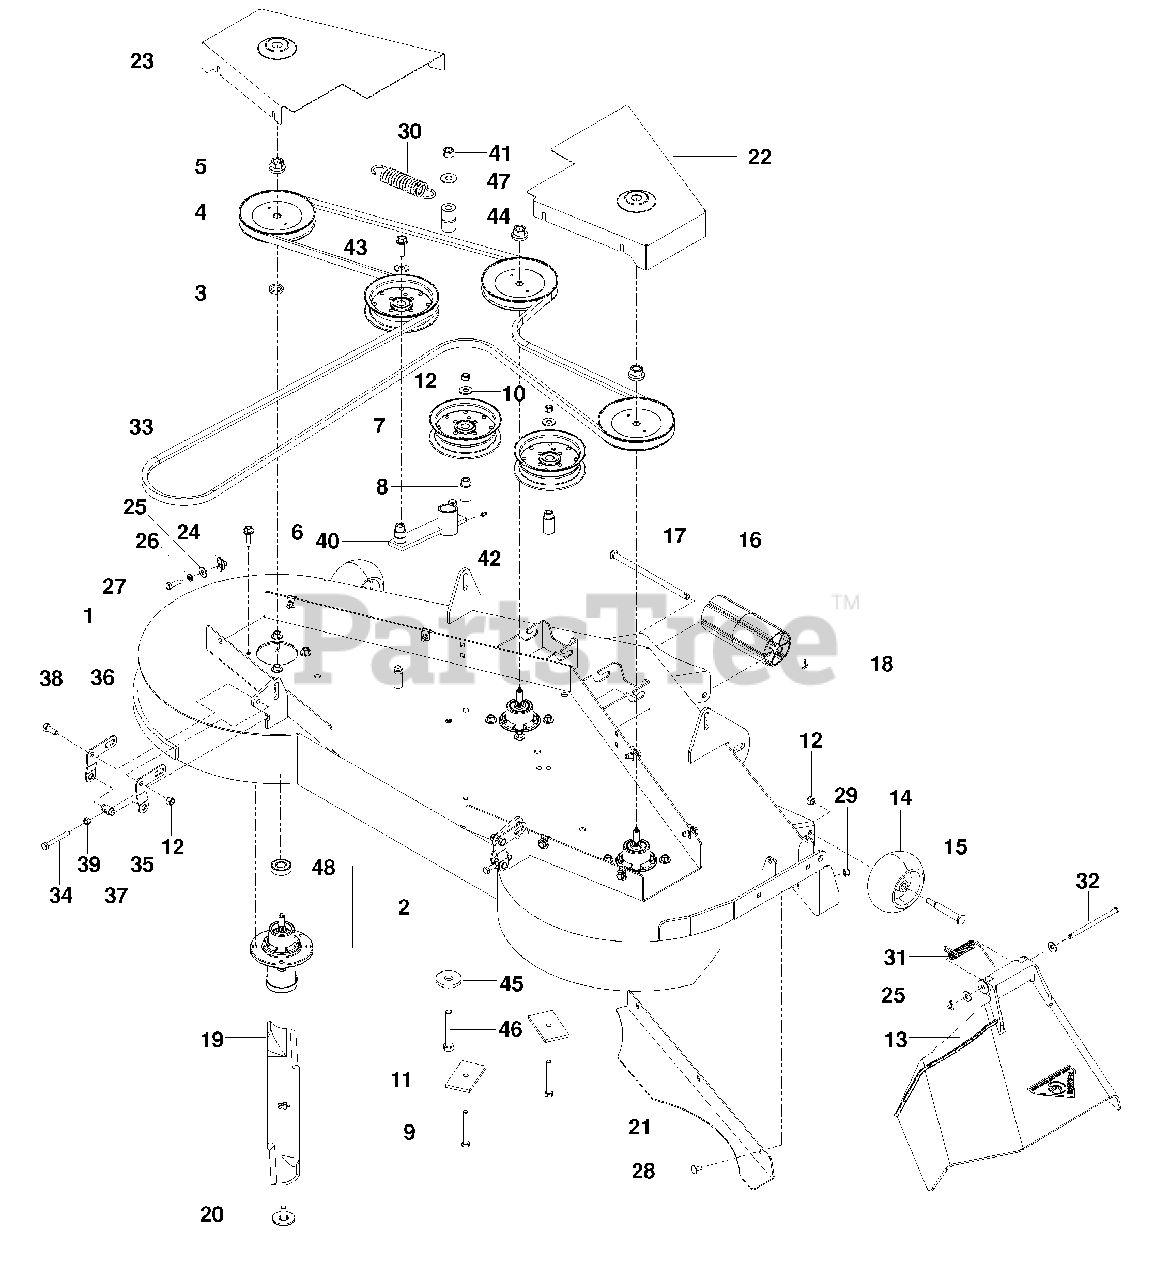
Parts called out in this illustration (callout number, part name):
1	DECK w/ SAFETY DECALS
2	HOUSING ASSEMBLY
3	WASHER-SPACER
5	NUT 9/16 TOP CENTER LOCK
6	SCREW, WASHER HEAD
7	PULLEY, IDLER
8	IDLER BUSHING
9	BOLT, HEX 3/8-16 x 3
10	WASHER 3/8 FLAT STD
11	PAD
12	NUT 3/8-16 HEX NYLOC
13	DISCHARGE CHUTE, 61"
14	WHEEL, GAUGE
15	BOLT, SHOULDER
16	ROLLER, NOSE, 48"
17	ROD, ROLLER, NOSE
18	PIN, COTTER 1/8 x 3/4
19	BLADE, 21"
20	BOLT 7/16 BLADE
21	CONFINEMENT PLATE
22	BELT SHIELD, RH
23	BELT SHIELD, LH
24	RETAINER, U TYPE 5/16-18
25	WASHER 5/16 STD FLT
26	WASHER 5/16 SPRING
27	HCS, 5/16-18 x 3/4
28	BOLT, RD HD 5/16-18 x 5/8
29	NUT 5/16-18 HEX NYLOC
31	SPRING, TORSION
32	PIN, CLEVIS 5/16
33	BELT, DECK
34	BOLT, HEX 5/16-18 x 2 1/2 TPBLT
35	PITCH, ADJUST, RT
36	PITCH, ADJUST, LT
37	TRUNION, PITCH
38	BOLT, HEX 3/8-16 x 1
39	NUT 5/16-18 HEX
40	IDLER ARM WELDMT
41	NUT 1/2 HEX NYLOC
42	ZERK
43	BOLT, HEX 3/8-16 x 1 WHIZLK
44	PIVOT BUSHING
45	HEAVY WASHER
46	BOLT, HEX 1/2-13 x 3 1/4
47	WASHER 1/2 STD FLT
48	BALL BEARING
